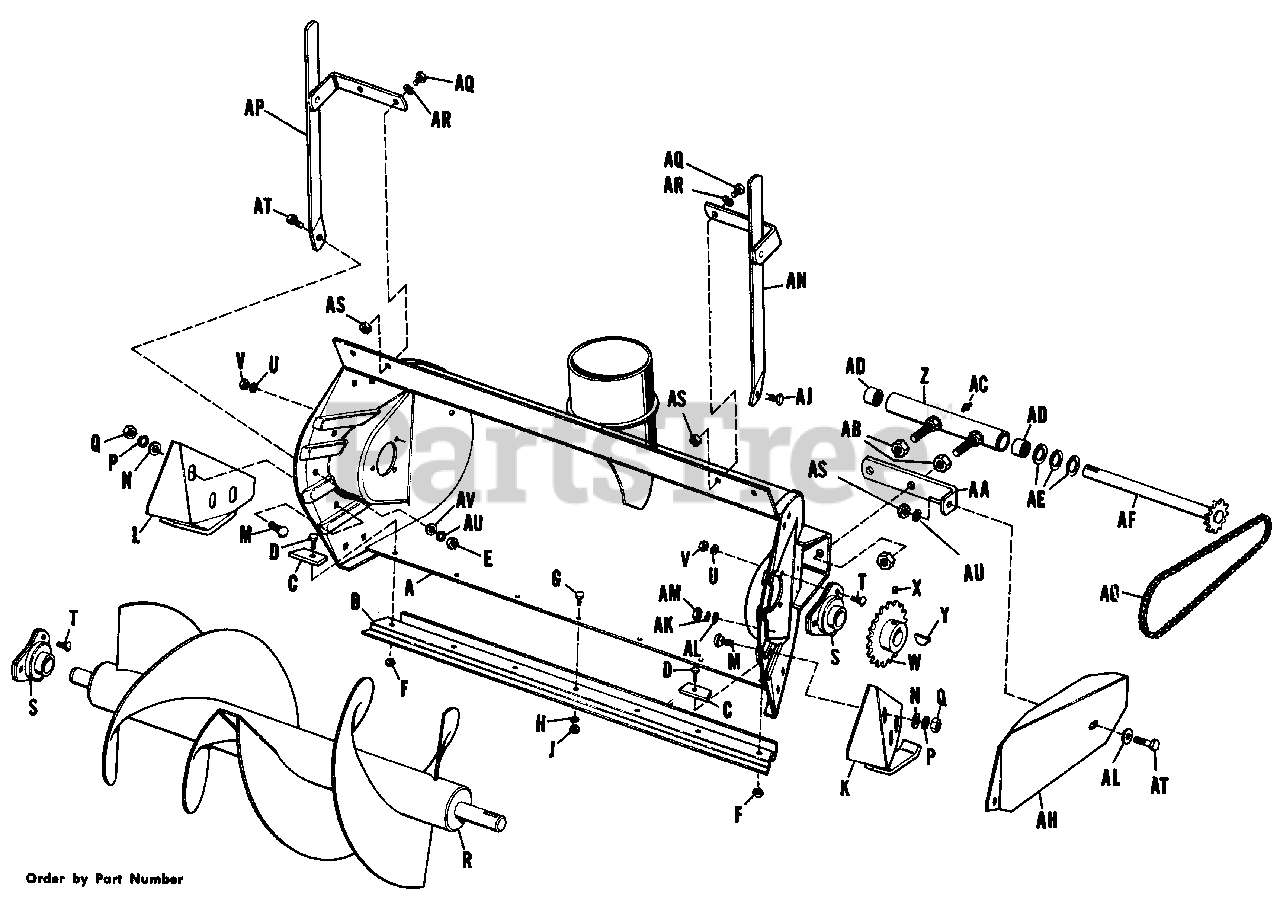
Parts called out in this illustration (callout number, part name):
A	Body Assembly
B	Scraper, Body
C	Clamp, Scraper
D	Capscrew, Hex Hd., 5/16"-18 NC x 3/4" lg.
E	Nut, Hex, Full, 5/16"-18 NC
F	Nut, Hex, Full, 5/16 "-18 NC
G	Capscrew, Hex Hd., 1/4"-20 NC x 1/2" lg.
H	Washer, Lock, 1/4"
J	Nut, Hex, Full, 1/4"-20 NC
K	Shoe Assembly, Left Hand
L	Shoe Assembly, Right Hand
M	Bolt, Carriage, 3/8"-16 NC x 3/4" lg.
N	Washer, Plain, 3/8"
P	Washer, Lock, 3/8"
Q	Nut, Hex, Full, 3/8"-16 NC
R	Rotor Assembly
S	Bearing, Ball
T	Capscrew, 5/16"-18 NC x 3/4" lg.
U	Washer, Lock, 5/16"
V	Nut, Hex, Full, 5/16"-18 NC
W	Sprocket, Rotor
X	Set Screw, Cup Point, Hex Socket, 5/16"-18 NC x 5/16" lg.
Y	Key, "Hi-Pro"
Z	Housing Assembly, Bearing
AA	Bracket, Chain Guard
AB	Nut, Hex, Full, 1/2"-13 NC
AC	Fitting, Grease
AD	Bearing, Needle
AF	Shaft Assembly
AG	Chain, Rotor
AH	Guard, Chain
AJ	Capscrew, Hex Hd., 5/16"-18 NC x 3/4" lg.
AK	Washer, Lock, 5/16"
AL	Washer, Plain, 5/16"
AM	Nut, Hex, Full, 5/16"-18 NC
AN	Cutter Assembly, Drift, Left Hand
AP	Cutter Assembly, Drift, Right Hand
AQ	Capscrew, Hex Hd., 5/16"-18 NC x 5/8" lg.
AR	Washer, Lock, 5/16"
AS	Nut, Hex, Full, 5/16"-18 NC
AT	Capscrew, Hex Hd., 5/16"-18 NC x 3/4" lg.
AU	Washer, Lock, 5/16"
AV	Washer, Plain, 5/16"
